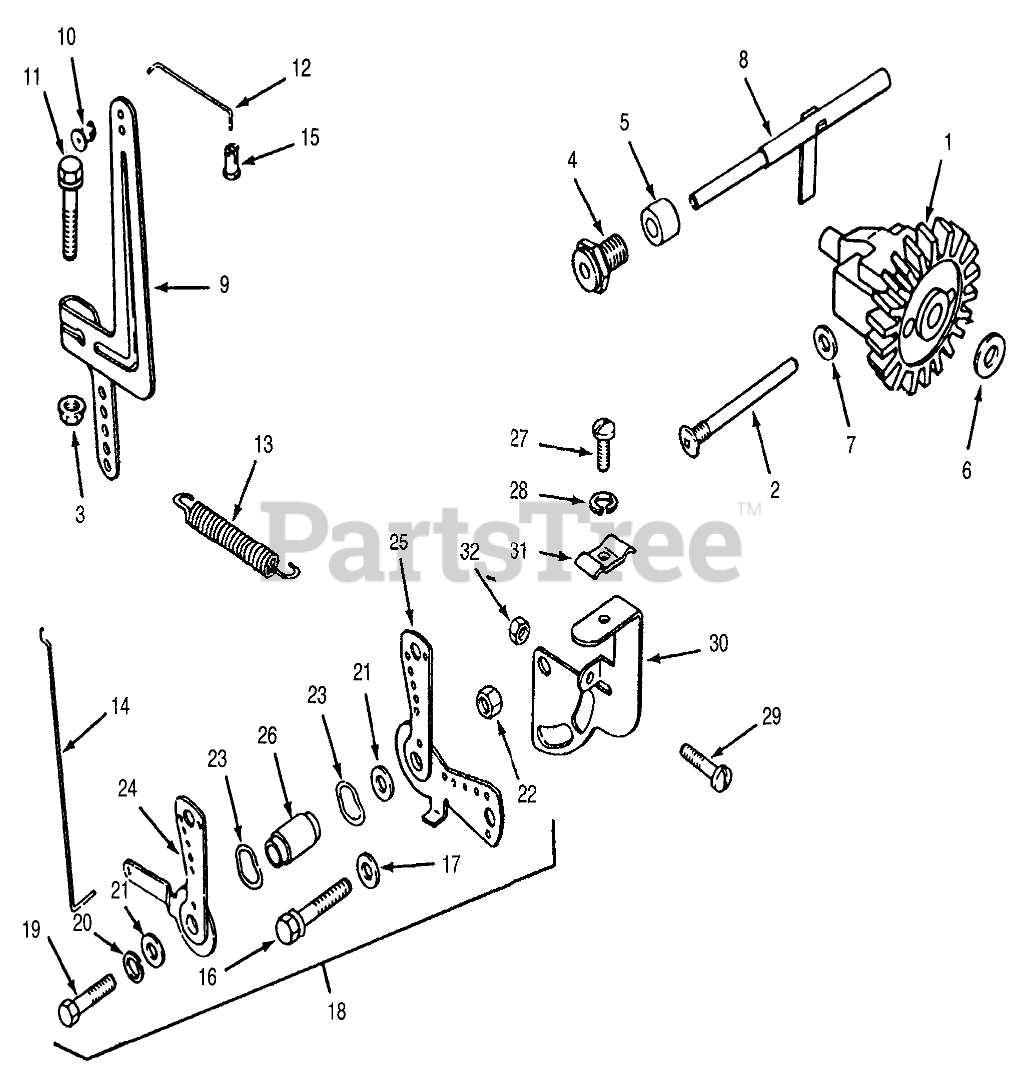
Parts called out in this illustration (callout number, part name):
1	Governor Gear Kit (Includes 24)
2	Pin-GovemorStop
3	Palnut
4	Bushing
5	Spacer
6	Washer
7	Washer-Plain
8	Kit-Governor Shaft
9	Lever-Governor
10	Screw
11	White Bushing
12	Unkage-Governor
13	Spring-Governor
14	Linkage-Choke
15	Yellow Bushing
16	H.C. Sems Screw 1/4-20 x 1/2
17	Washer
18	Choke Lever Assembly (Includes Items 37 thru 44)
19	Screw
20	Washer
21	Washer
22	Nut
23	Washer
24	Choke Control Lever
25	Throttle Control Lever
26	Spacer
27	Screw
28	Washer
29	Screw
30	Bracket
31	Clamp
32	Nut
